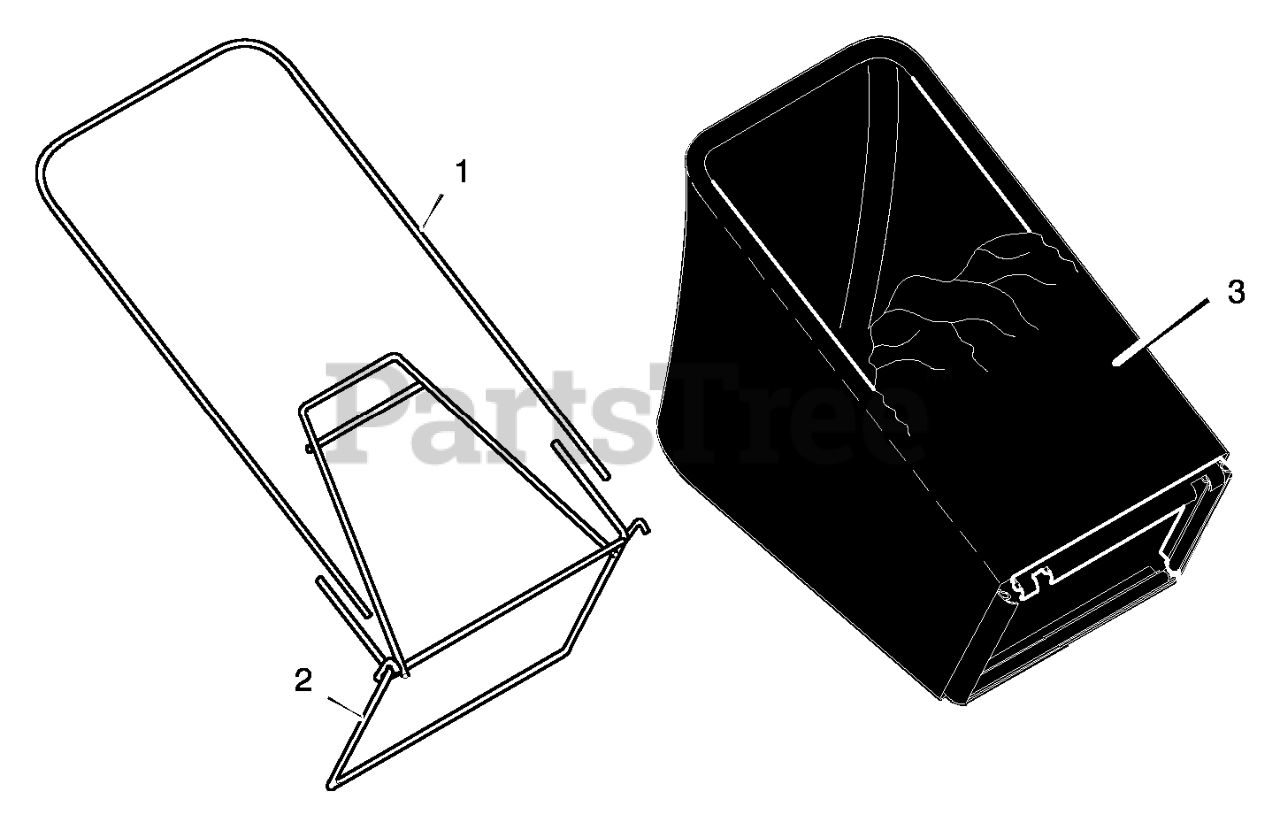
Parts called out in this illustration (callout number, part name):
1	Frame, Top
2	Frame Assembly
3	Bag, Cloth - Black
